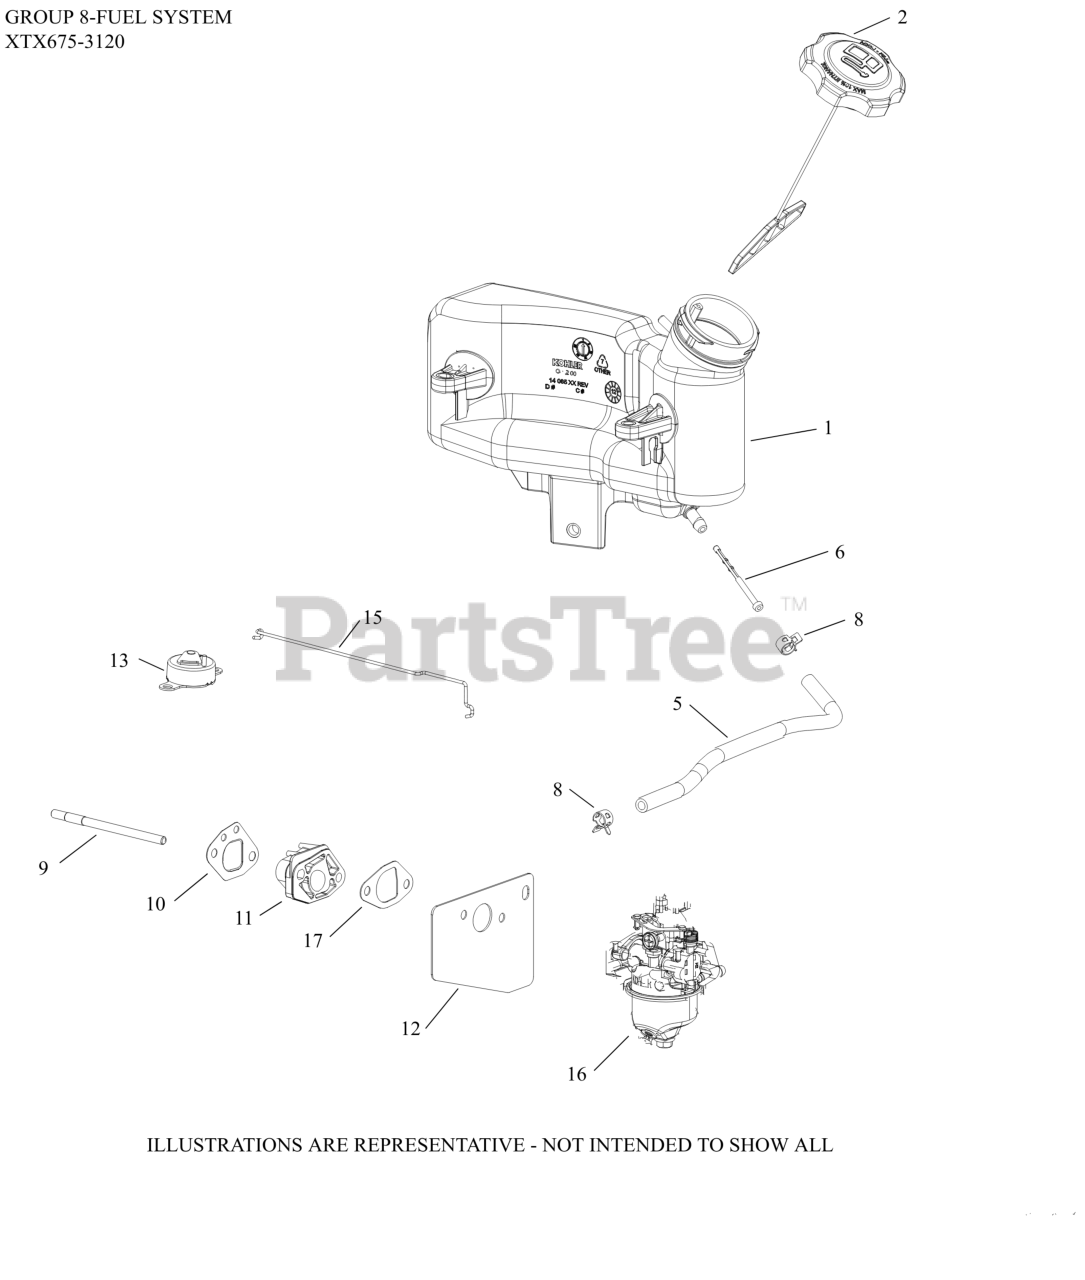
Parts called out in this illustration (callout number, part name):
1	TANK, FUEL
2	FUEL CAP ASSEMBLY
5	HOSE, FUEL LOW-PERMEATION (CKY)
6	FILTER, FUEL IN-NIPPLE
8	CLAMP, HOSE (NON-CALIF)(#1423710S)
9	STUD,M6X1.0X100.2MM
10	GASKET, SPACER - USE 14 041 24-S
11	SPACER, CARBURETOR
12	KIT, CARBURETOR HEAT SHIELD GASKET
13	ARM ASSEMBLY, AUTO CHOKE
15	LINKAGE, AUTO CHOKE
16	KIT,CARB (HUAYI)
17	KIT, INTAKE GASKET
NI	KIT, CARBURETOR REPAIR (HUAYI)
NI	KIT, HIGH ALTITUDE 4000-8000'
